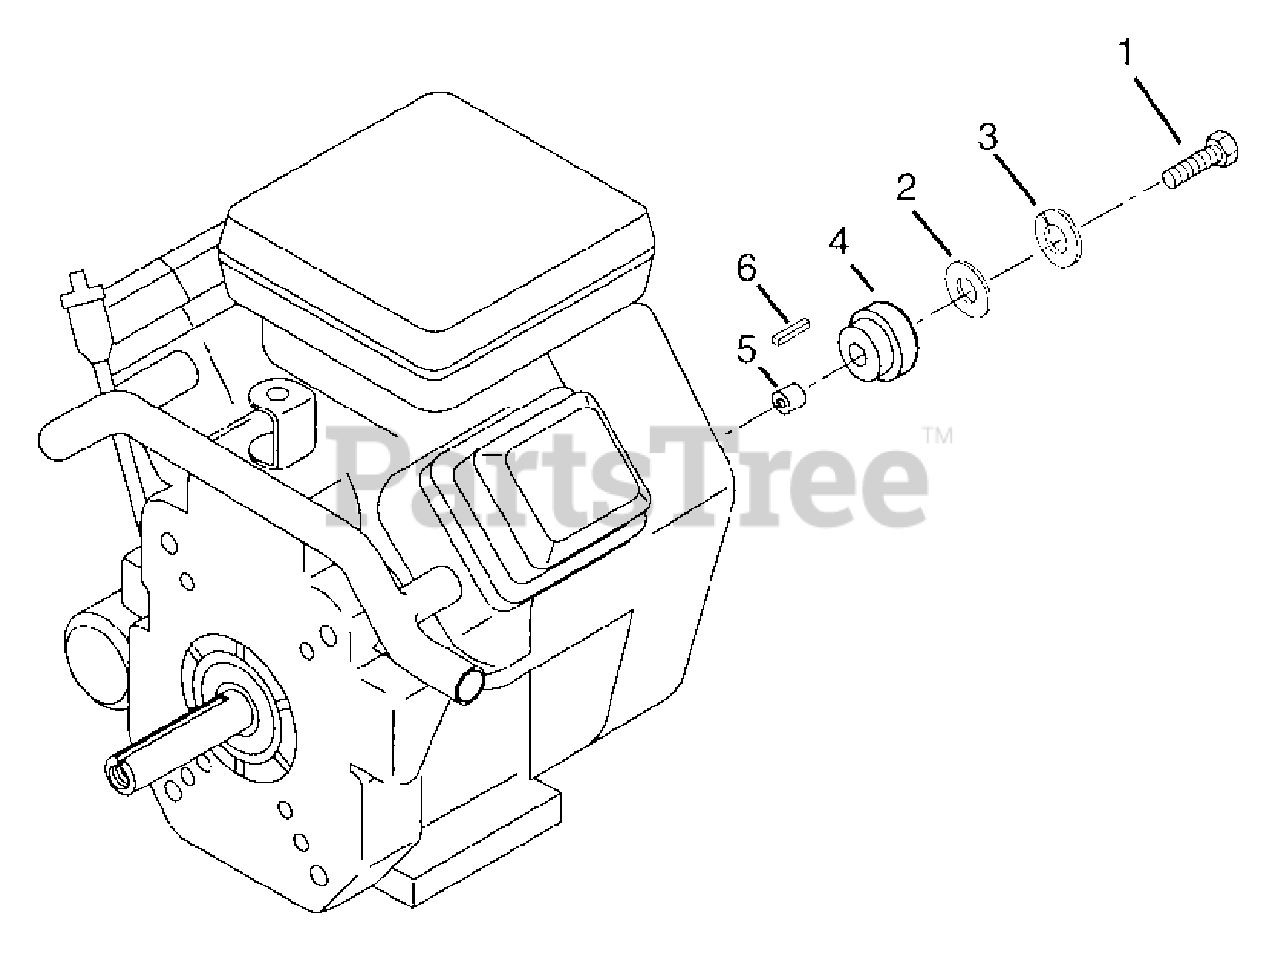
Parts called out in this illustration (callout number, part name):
1	Bolt-Hex .38-24 x 1.25 Grade 8
2	Washer-Flat-Steel .390 x 1.5 x .125
3	Washer-Locking .375 x .115
4	Sheave-Engine
5	Spacer 1.01 x 1.25 x .645
6	Key-Straight .25 x 2.0 x .25
